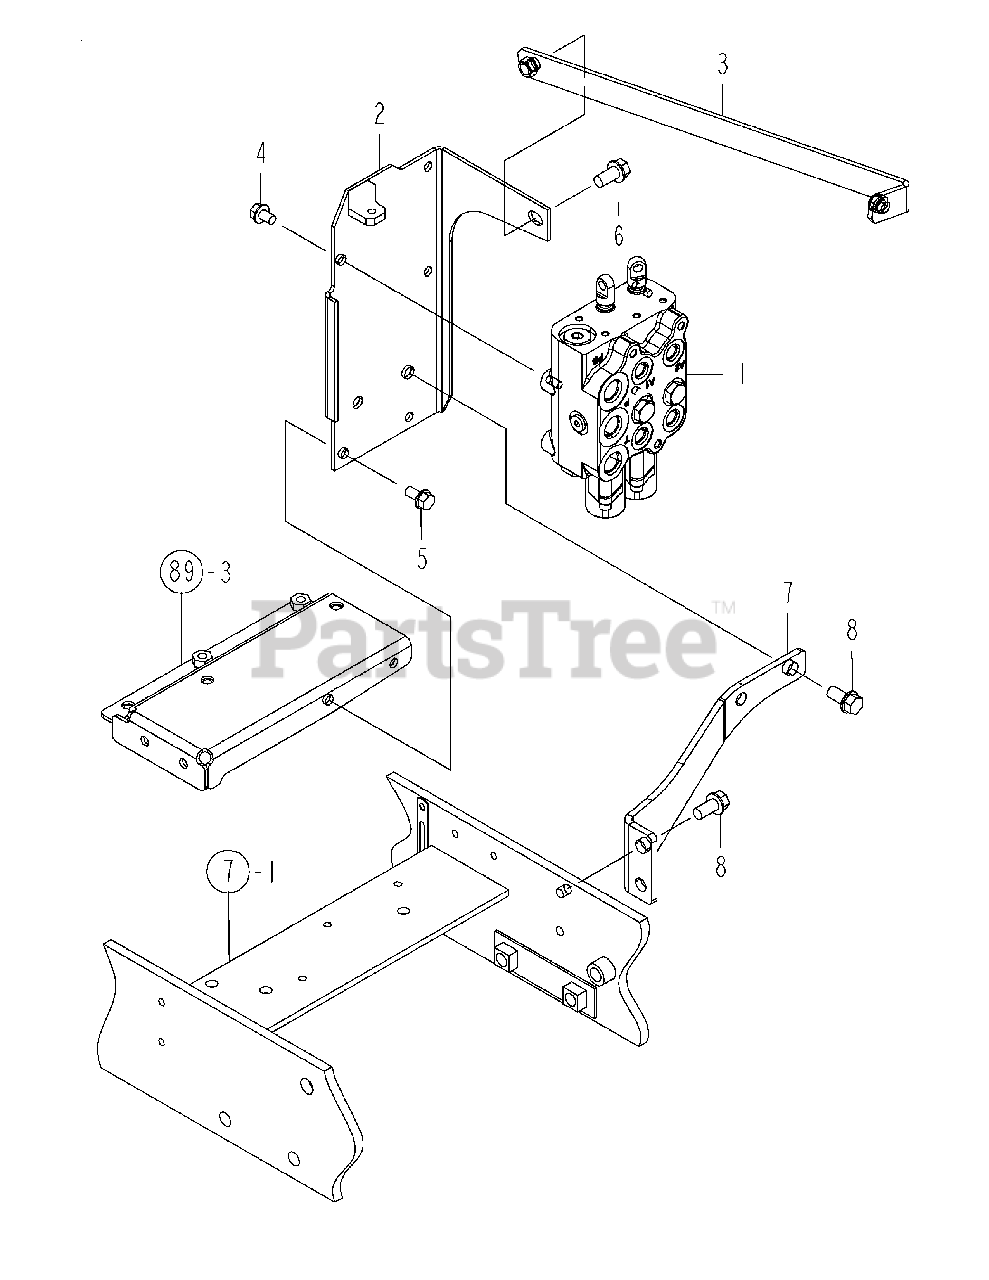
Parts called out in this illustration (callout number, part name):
1	VALVE CMP, LOADER
2	STAY, SCV VALVE
3	PLATE CMP, SCV VALVE
7	PLATE, SUPPORT SCV
